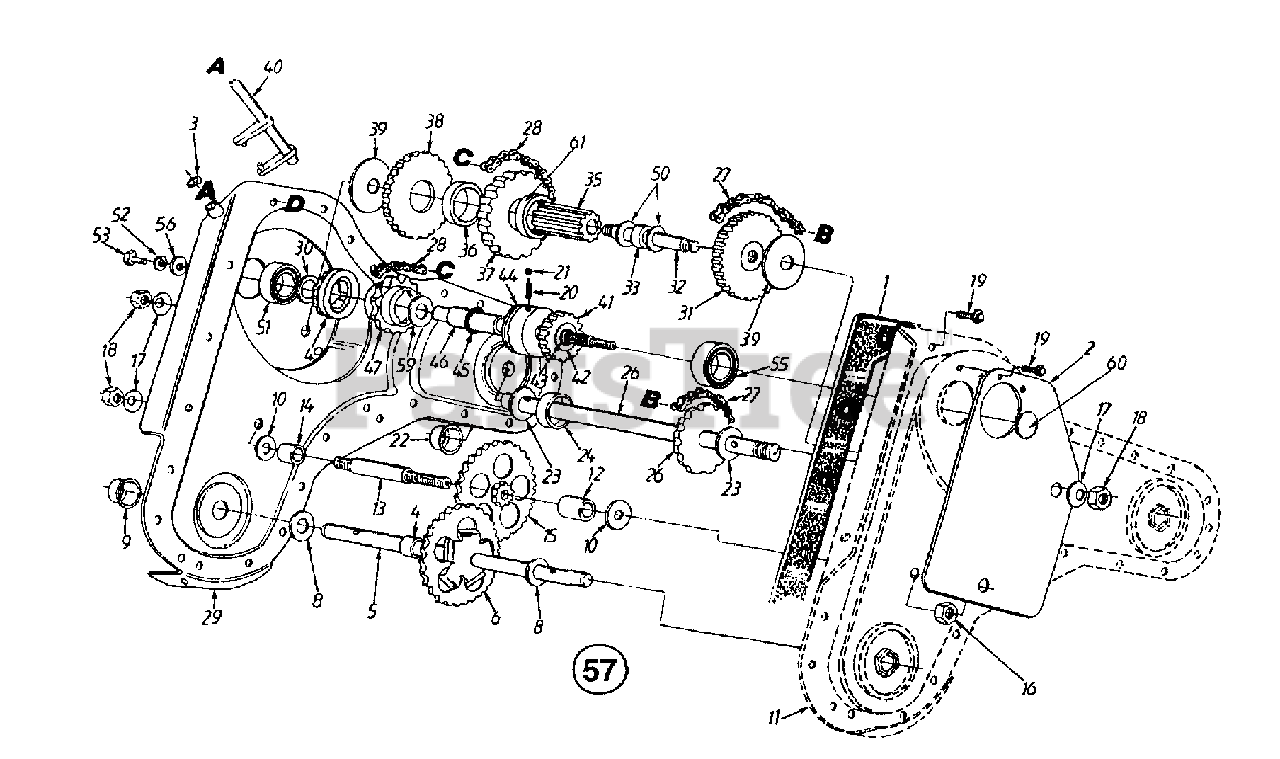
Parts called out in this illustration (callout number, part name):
1	Chain Case Gasket
3	Snap Ring
4	Spacer.735" I.D. x .886" O.D.
5	Wheel Shaft
6	Spur Gear 46T
8	Fl-Wash. .76" I.D. x 1.5" O.D.
9	Shaft Seal
10	Thr.Wash 445 I.D.x1.92 O.D.x
13	Jack Shaft 2.06" Lg.
14	Spacer .635" I.D. x 1" O.D. x .37" Thk.
15	Gear Idler Ass'y.
16	Hex Patch L-Nut 7/16-20 Thd.
17	Bell-Wash. .45" I.D. x 1" O.D.
18	Hex Nut 7/16-20 Thd.
19	Hex Wash. Hd. TT-Tap Scr. 1/4-20 x .5" Lg.
20	Spring Detent
21	Ball Detent
22	Shaft Seal
23	Thrust Wash. 1.03" I.D. x 1.62"
24	Spacer 1" I.D. x 2" O.D. x .5" Thk.
26	Tine Shaft Ass'y.
27	Chain #50 5/8" Pitch x 52 Links-Endless
28	Chain-#41 1/2" Pitch x 30 Links-Endless
30	Fl-Wash. 7/16" I.D. x 1-3/8" O.D.
31	Gear and Sprocket Ass'y.
32	Jack Shaft 5" Lg.
33	Spacer.636" I.D. x .86" O.D.
35	Spur Gear 10T
36	Spacer 1.5" I.D. x 1.76" O.D.
37	Sprocket-#41 Chain
38	Reverse Gear 46T
39	Thrust Wash. .445" I.D. x 1.92"
40	Shifter Ass'y.
41	Spur Gear 17T
42	Fl-Wash. .69" I.D. x 1.06" O.D.
43	Wire Ring
44	Clutch Collar
45	Retaining Ring .875" Shaft
46	Drive Shaft
47	Sprocket 11T
49	Spur Gear 16T
50	Fl-Wash. 5/8" I.D. x 1" O.D.
51	Ball Bearing .669" I.D.
52	L-Wash. 1/4" I.D.
53	Hex Bolt 1 /4-20 x .62" Lg.
55	Ball Bearing
56	Fl-Wash. .281" I.D. x .875" O.D.
57	Gear Case Ass'y. Comp.
59	Fl-Wash. .88" I.D. x 1.5" O.D.
60	Button Plug
61	Spacer 1.52" I.D.
